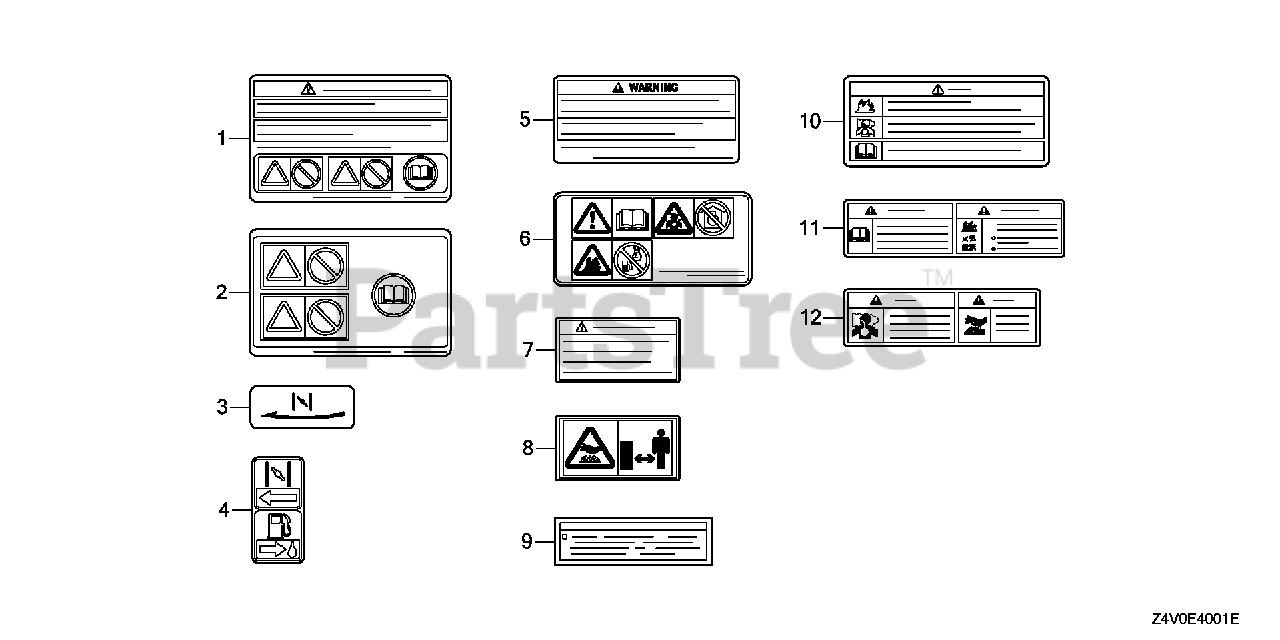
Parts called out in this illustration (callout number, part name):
5	MARK, OPERATOR CAUTION (FRENCH)(MADE IN THAI)
6	MARK, OPERATOR CAUTION (PICTOGRAPH)
7	MARK, EX. CAUTION (FRENCH)
8	MARK, EX. CAUTION (PICTOGRAPH)
